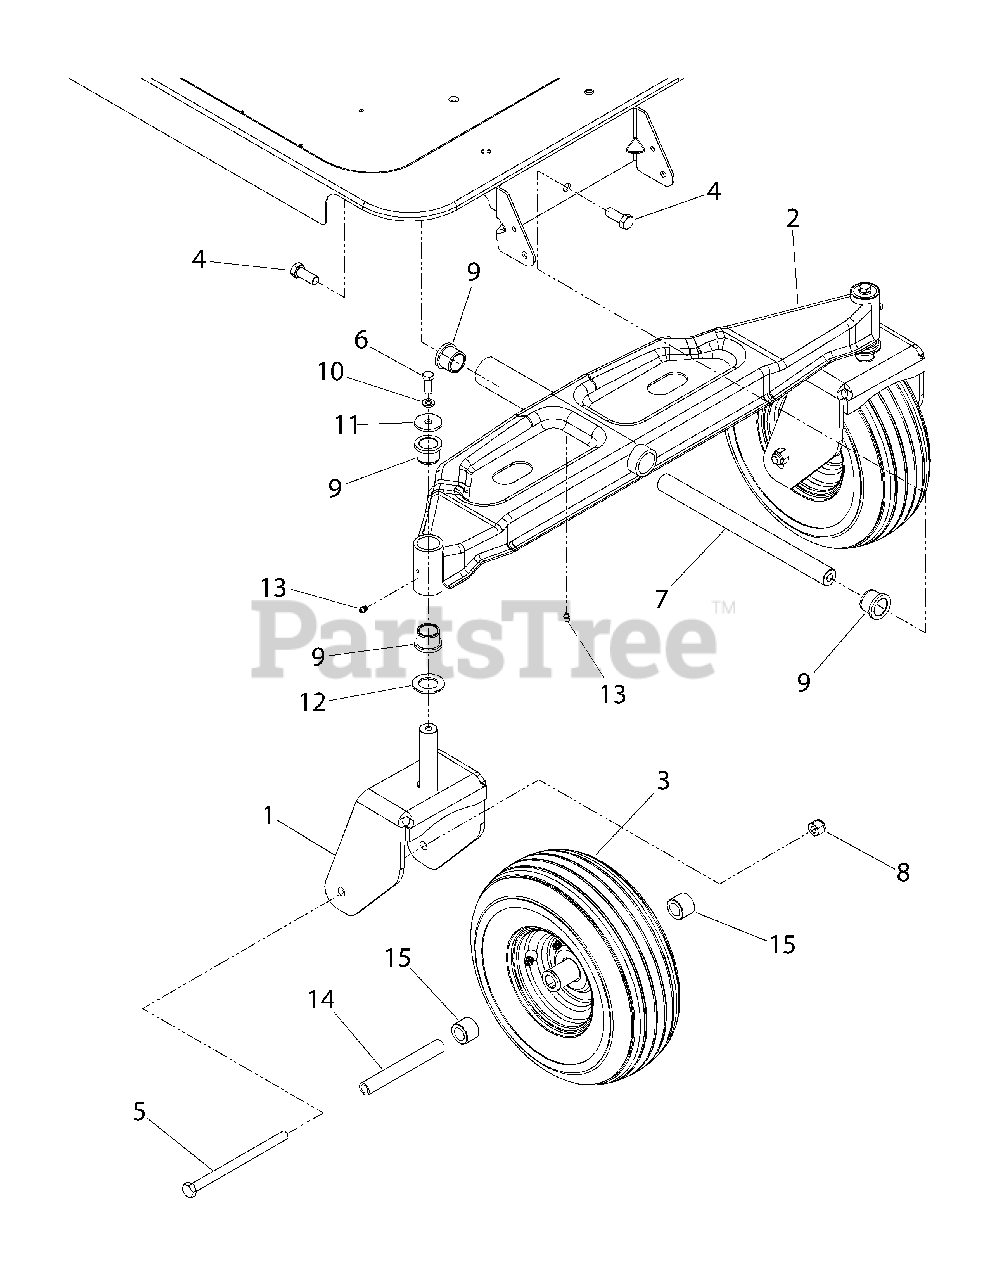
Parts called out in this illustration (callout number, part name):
4	Screw, Hex Lock, 1/2-13 x 1.25 GR5
5	Screw, Hex Cap, 1/2-20 x 7.25 Gr5
6	Screw, Hex Cap, 3/8-16 x 1.0 GR5
7	Shaft, Axle
8	Nut, Hex Insert Lock, 1/2-13 GRB
9	Bearing, Flange, 1.0 x 1.246
10	Washer, Lock, 3/8
11	Washer, Flat, .39 x 1.5 x .134
12	Washer, Flat, 1.0 x 1.75 x .10
13	Fitting, Lube, 3/16 Drive
14	Spacer, .51 x .75 x 5.825
15	Hub, .76 x 1.23 x .92
